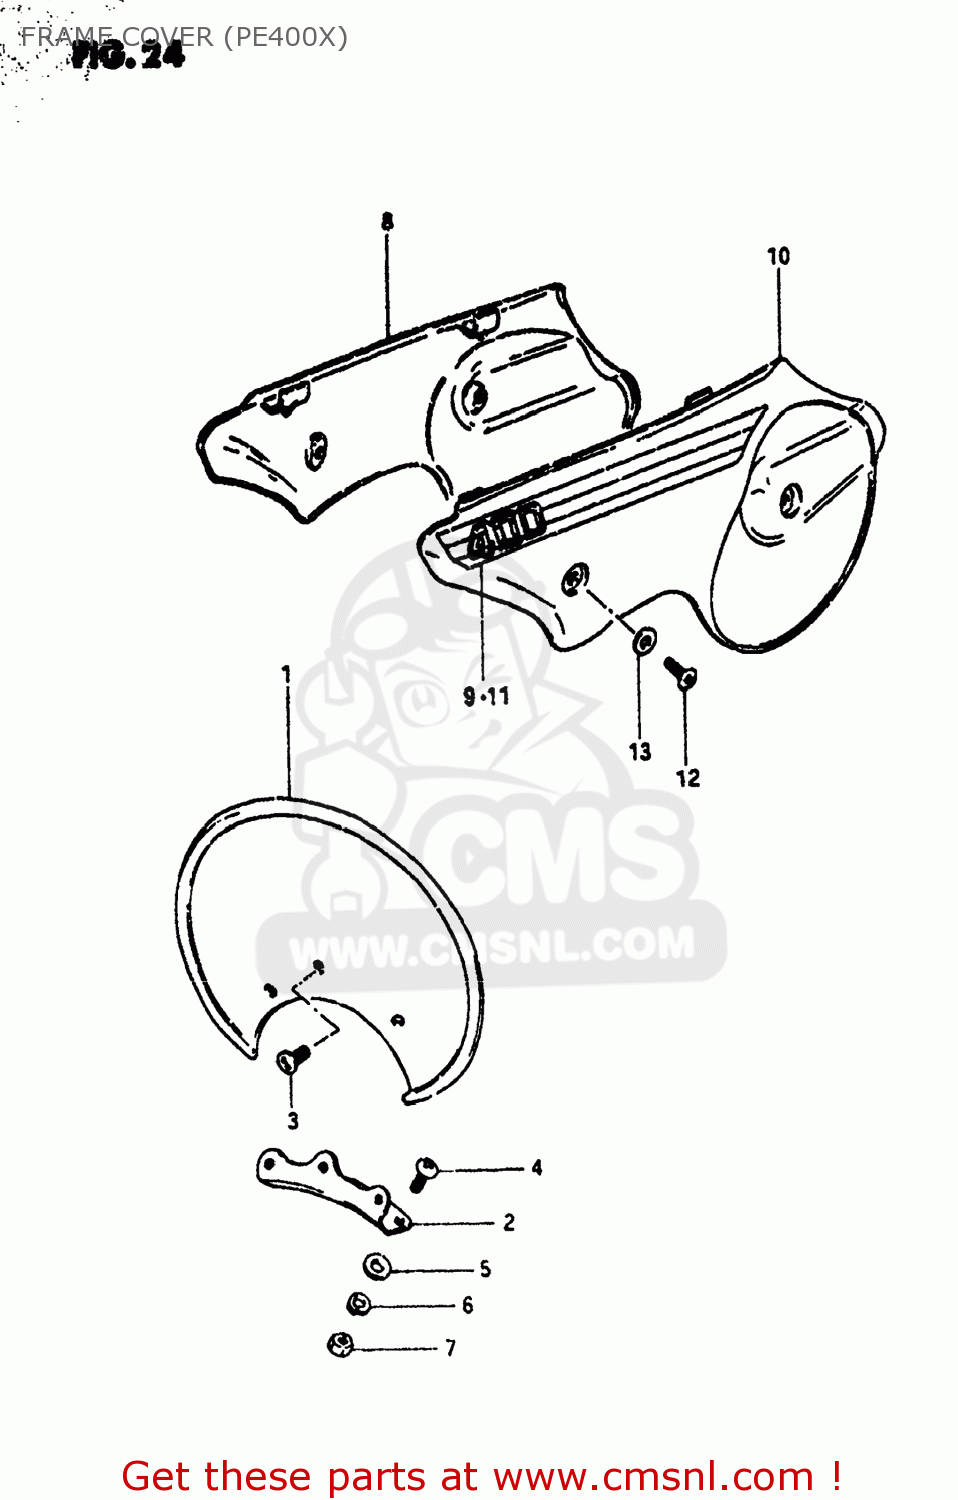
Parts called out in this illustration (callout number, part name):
1	PLATE,NUMBER,FRONT
2	BRACKET FR NUM PLATE
3	SCREW
4	SCREW
5	WASHER
6	LOCK WASHER
7	NUT
8	COVER,FRAME,R(YELLOW)
9	TAPE,FRAME COVER
10	COVER,FRAME,L(YELLOW)
11	TAPE,FRAME COVER
12	SCREW
13	SPACER
